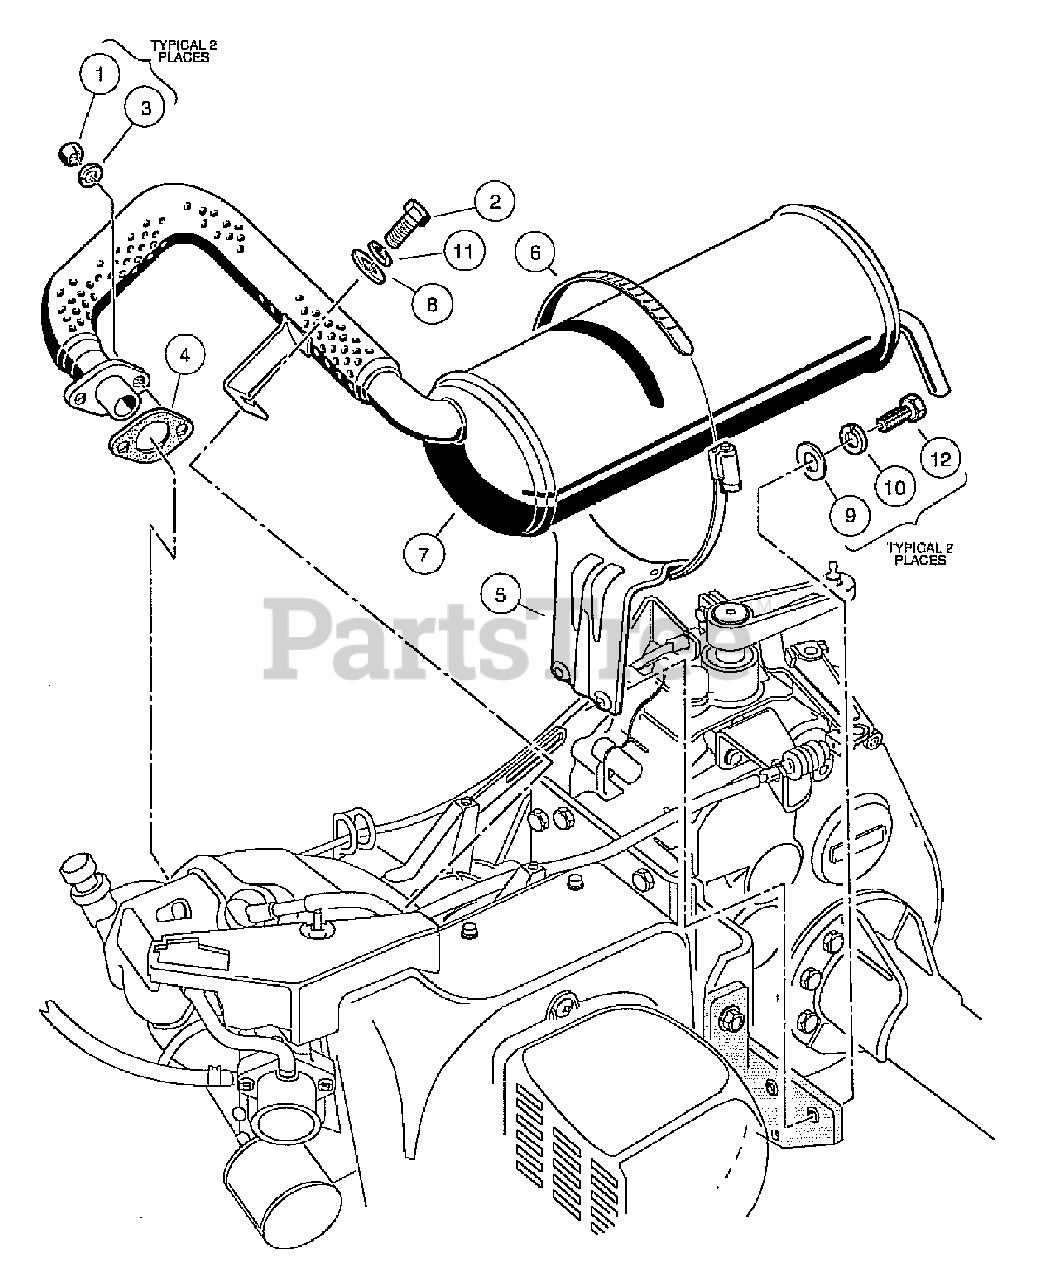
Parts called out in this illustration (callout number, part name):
1	Nut, M8-1.25 Hex
2	Screw, M8-125 X 22 Hex Gr.8.8
3	Lockwasher, 8mm Split
4	Gasket, Exhaust
5	Bracket, Muffler Mounting
6	Clamp, 5" Muffler Hose
7	Exhaust System, FE290
8	Washer, 5/16 Type A Flat
9	Washer, 1/4 Type A Narrow Flat
10	Lockwasher, 1/4 Helical Split
11	Lockwasher, 5/16 Split
12	Screw, 1/4-20 X 0.75 Hex-Head Cap
